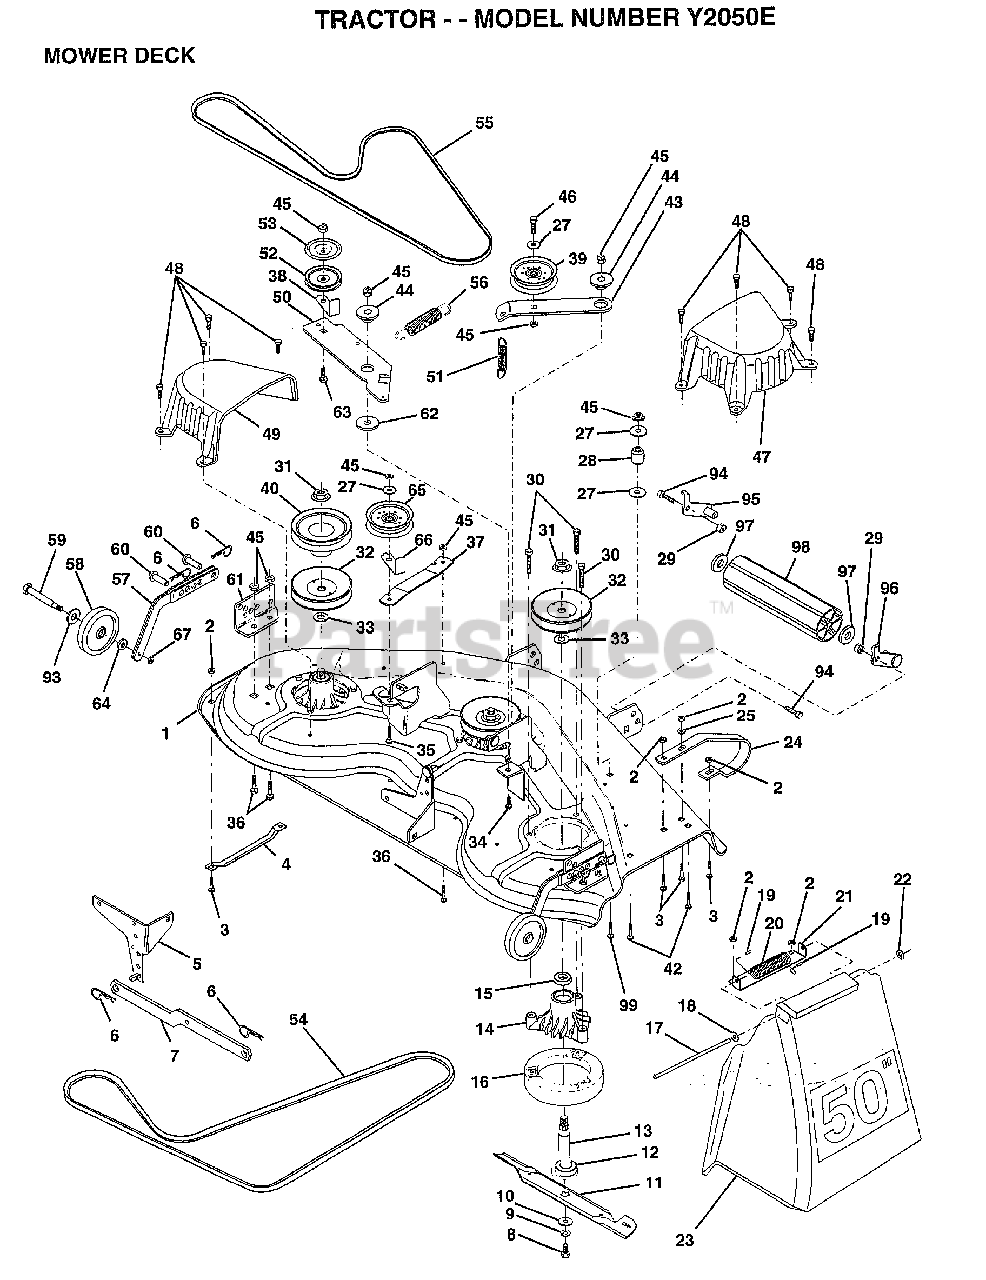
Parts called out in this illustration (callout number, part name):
1	DECK ASM MWR 50VT
4	RUNNER-LH M
5	BRKT.ASM.SW.44/50
8	BLADE BOLT
10	WASHER.HARD.BLADE
11	"BLADE.50"" HD"
12	BEARING.BALL
13	SHAFT.ASM.W/BRNG
14	HOUSING.MAND.44.V
15	BEARING
16	STRIPPER RND MWR
17	ROD-HINGE T
18	WASHER
19	CAP-SLEEVE LT
20	SPRING TORSION
21	BRKT DEFLECTOR
22	NUT PUSH M
23	DEFLECTOR
24	"RUNNER RH 50"" DK"
25	WASHER M
27	WASHER
29	NUT
33	WASHER
34	BOLT.3/8-14X1.25
35	BOLT
36	BOLT D
37	STIFFENER.ARM.IDL
39	FLAT IDLER PULLEY
40	"PULLEY.DRIVEN.44"""
42	BOLT
43	"ARM.IDLER.SEC.44"""
44	SPACER RETAINER
47	"COVER.MAND.RH.44"""
48	SCREW.1/4-20X5/8
49	COVER.MANDREL.LH
50	ARM.IDLER.PRIMARY
51	"SPRING.SEC.44""VEN"
52	PULLEY.IDLER.VGRO
53	SHIELD.IDLER.44.V
54	BELT V PRIM 50
55	BELT.V.GDRIVE.95
56	SPRING.EXT.DECK.
57	BAR.ASM.GUAGE.WHL
58	WHEEL.GAGE.BLK.PL
59	BOLT M
60	PIN.CLEVIS
61	BRACKET.GUAGE.WHL
62	HARDENED WASHER
63	BOLT.3/8-16X1.50
64	WASHER
65	IDLER-FLAT T
67	LOCKNUT
93	WASHER
94	BOLT
97	WASHER
99	BOLT
